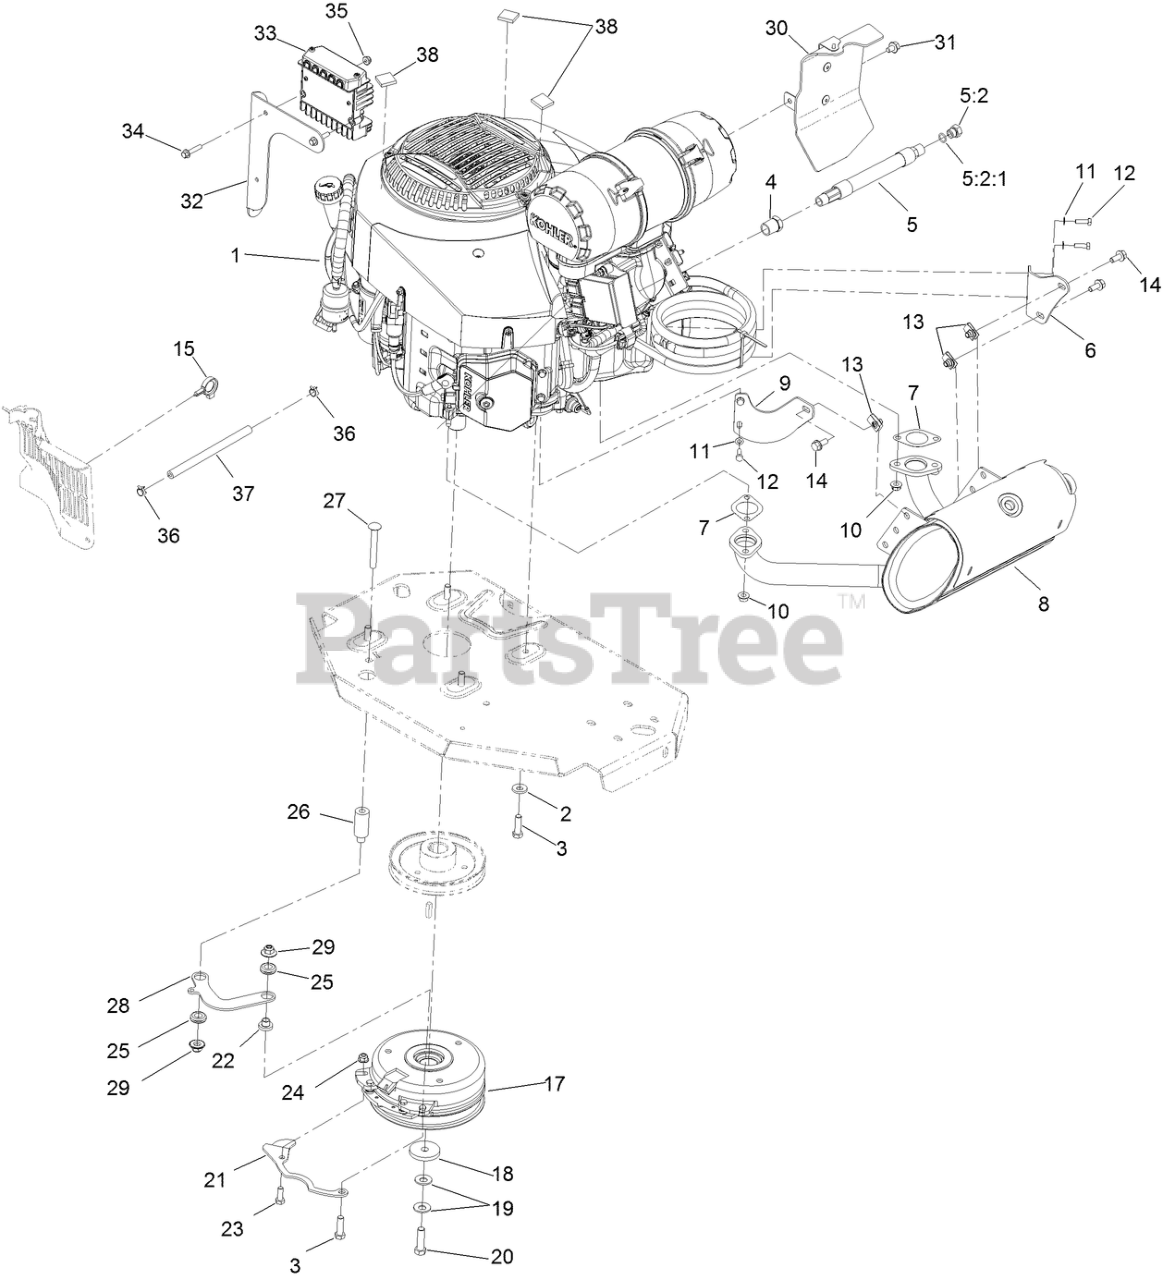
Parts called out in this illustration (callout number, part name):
2	WASHER-BELLEVILLE
3	SCREW-HH
4	BUSHING
5	OIL DRAIN HOSE ASM
5:2	PLUG-HH
5:2:1	O-RING
6	BRACKET-MUFFLER
7	GASKET-EXHAUST
8	MUFFLER-940-980 KOH EFI
9	BRACKET-MUFFLER, FRONT
10	NUT-FLANGE, LOCK
11	WASHER-SPRING
12	SCREW-HH
13	NUT-U
14	SCREW-HHF
15	CLAMP-HOSE
17	CLUTCH KIT
18	WASHER-CLUTCH
19	WASHER-SPRING
20	SCREW-HH, W/LOCTITE
21	BELT-GUIDE
22	SPACER
23	SCREW-HH
24	NUT-HF, NI
25	GROMMET-RUBBER
26	SPACER
27	SCREW-CARR
28	LINK-ANCHOR, CLUTCH
29	NUT-FLANGE, NI
30	BAFFLE ASM
31	SCREW-HHF
32	MOUNT-REGULATOR
33	REGULATOR AND RECTIFIER ASM
34	SCREW-HHF
35	NUT-HF
36	CLAMP-HOSE
37	HOSE-FUEL
38	VELCRO
